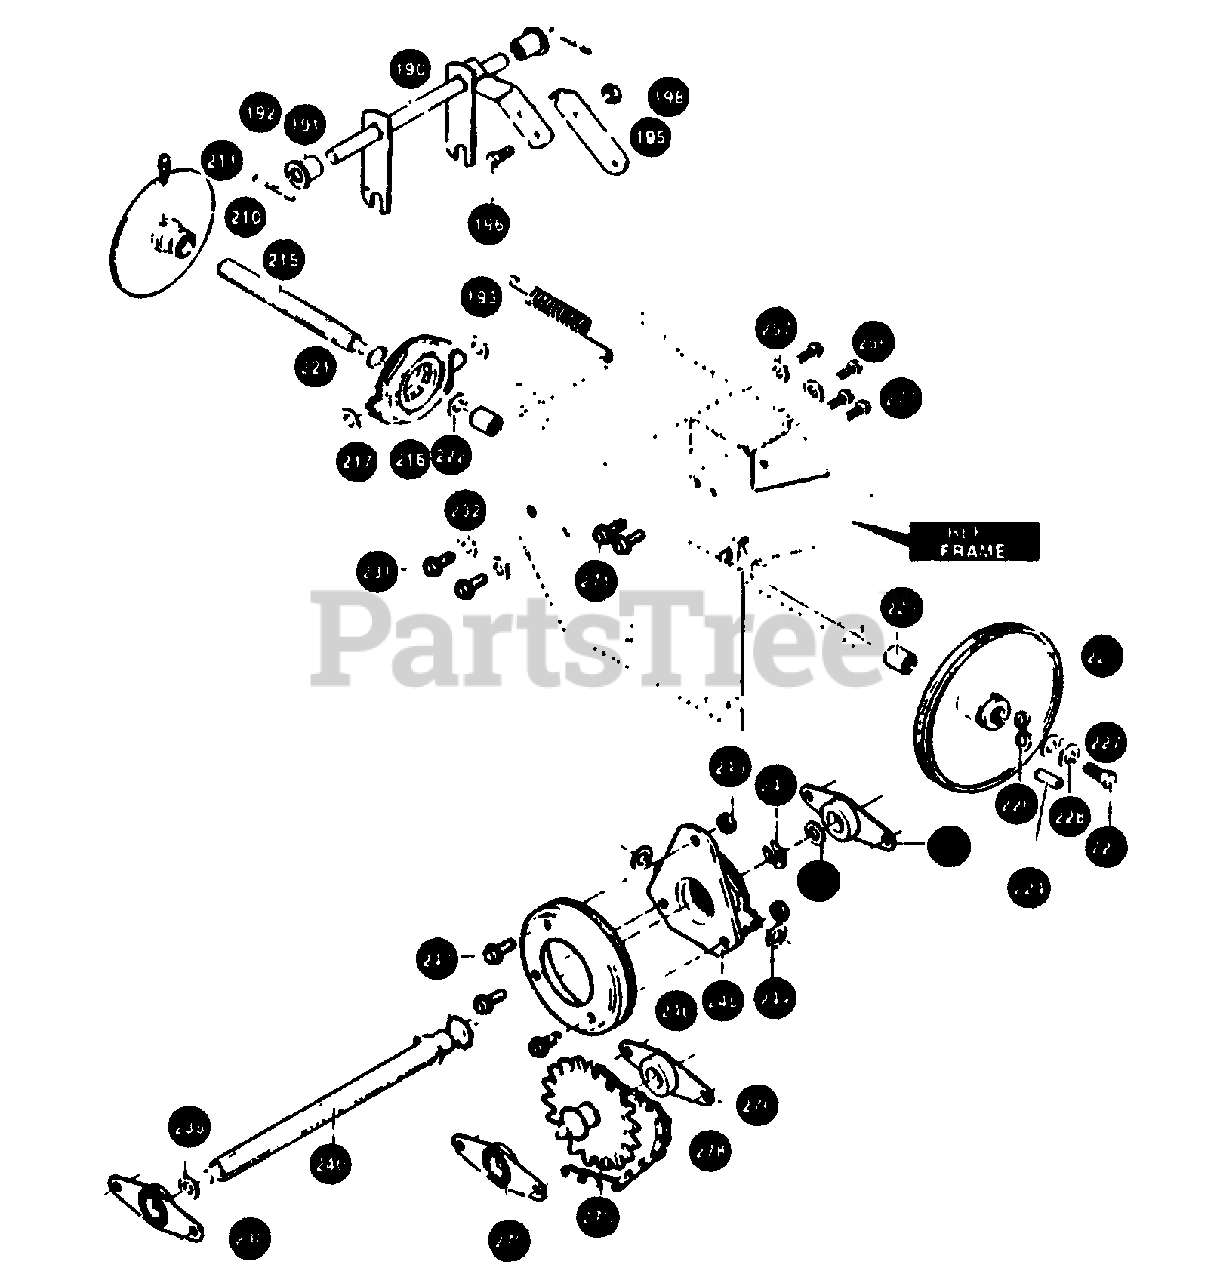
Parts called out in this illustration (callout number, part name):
190	LEVER, ASSY TRACTION
191	BEARING, FLANGE
192	PIN, COTTER
193	SPRING, RETURN
195	LEVER, SPRING
196	SCREW, 1/4-20X .83 HHCFT
198	NUT, 1/4-20 REGHEXCTRLK
210	DISC, ASSY FRICWHL
211	ZERK, GREASE
215	SHAFT, HEX TRACTION
216	BEARING, TRUNION 1.25 ID
217	WASHER, FLAT .53 X1.00X.083
221	RING, RETEX
222	FLATWASHER .680 X 1 .12 X .060
223	BEARING, BALL
224	KEY, SQUARE.18SQ X.63LG
225	PULLEY, V3L 6.50 X .56
226	WASHER, WAVE
227	WASHER, FLAT .281 X1.00X.083
228	WASHER, 263X.49X.07
229	SCREW, 1/4-20X .75 HHC
230	BEARING & RETAINER, ASSY
231	SCREW, 5118-18X .50
232	WASHER 328X.60X.09
235	WASHER, SP .502X .75X.0605
240	HEX, ASSY #40-8TW/PBRG
243	RING, RETEX
244	WASHER, FLAT.53 X1.00X.063
245	BEARING, TRUNION
246	WHEEL, ASSY FRICTION DISC
247	SCREW, 1/4-20X .63 HHCFT
249	NUT, 1/4-20 HEX KEPS
250	WASHER, SP .502X .75X.0605
255	BEARING & RETAINER, ASSY
256	SCREW, 5/16-18X .50
257	WASHER, .328X.60X.09
270	BEARING & RETAINER, ASSY
271	SCREW, 5/16-18X .50
275	JACK, ASSY #41-36T&7T
276	BEARING & RETAINER, ASSY
277	SCREW, 5/16-18X .50
278	CHAIN, ROLLER 442 X 40P
